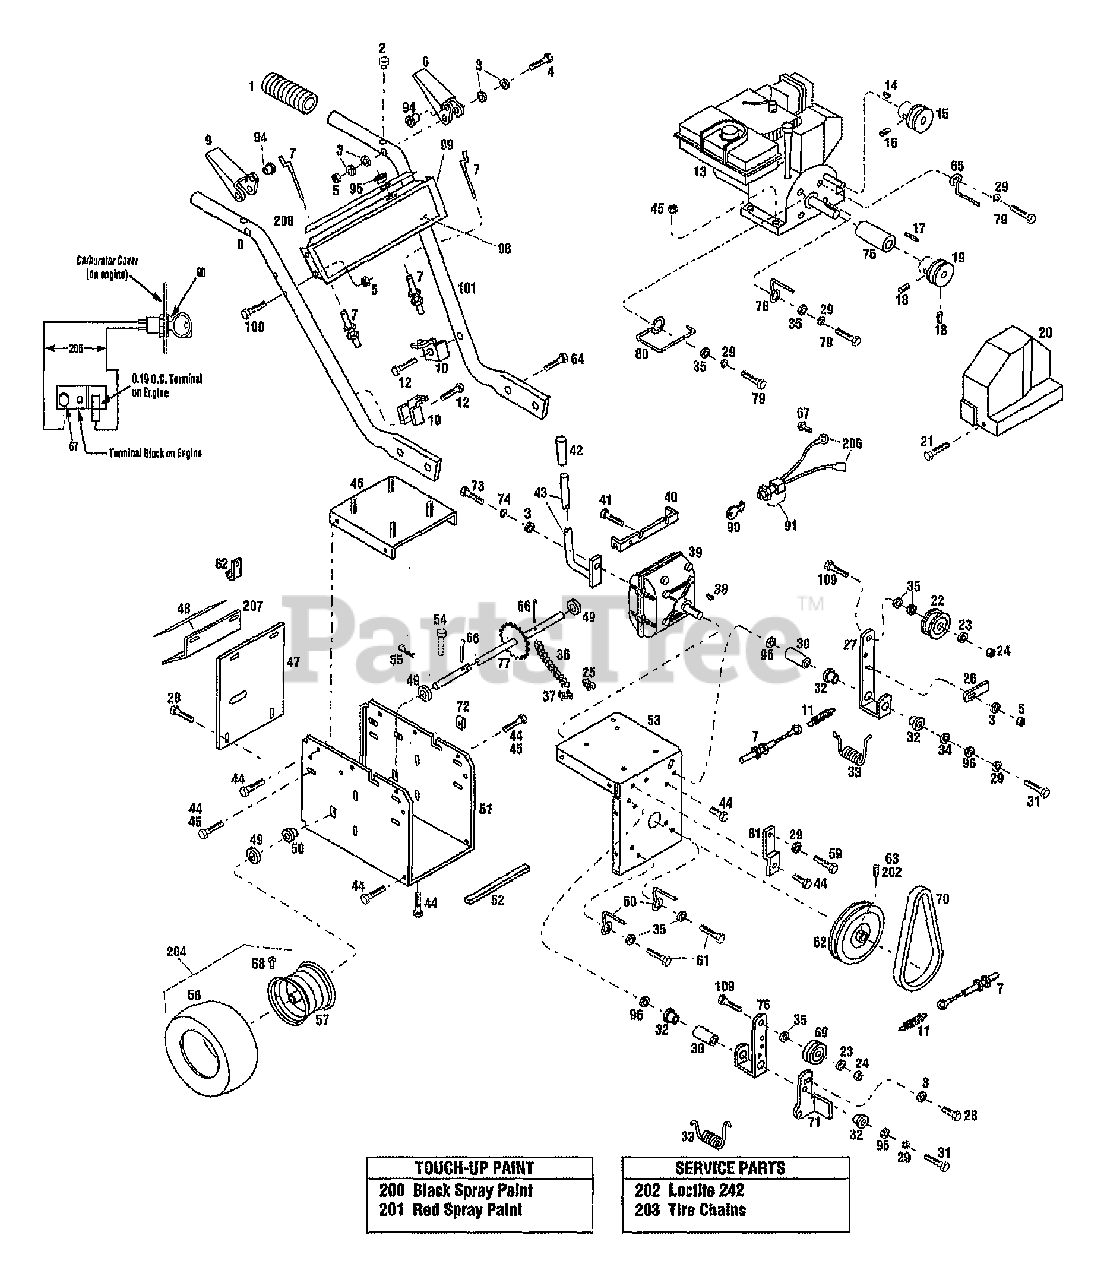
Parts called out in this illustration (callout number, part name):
1	GRIP-FLEX
2	BUMPER-RUBBER
3	WASHER-FLAT 1/4 SAE
4	SCR-HH 1/4-20X1.75 G5 ZP
5	NUT-HT LK 1/4-20
6	LEVER-CONTROL
7	CABLE-CONTROL
8	HANDLEBAR-RH
9	LEVER-CONTROL
10	BRKT-CONTROL CABLE
11	SPRING-EXT
12	SCR-FLANGE 1/4-20X3/4 GR5
13	ENGINE, TECUMSEH MODEL HSK60
14	KEY-WOODRUFF 1/8 X 5/8
15	PULLEY-PTO
16	SCR-SET 1/4-20X3/8 CONE
17	KEY-.187 SQ X .75
18	SCR-SET 5/16-18 X 5/16
19	PULLEY-ENGINE
20	COVER-BELT SC
21	SCR-TRUSS #10-24 X 5/8
22	PULLEY-IDLER
23	WASHER-LK .375 @ DEPL
24	NUT-HEX 3/8-16 ZP
25	LINK-OFFSET
26	STOP-IDLER ARM
27	ARM-IDLER WELD
28	SCR 1/4-20X.5 FL SELF TAP
29	WASHER-LK .312 ZP
30	SPACER-.5X.334X1.79
31	SCR-HH 5/16-18X2.5
32	BUSHING-.5X.5 NYLON FLNG
33	SPRING-TORSION
34	WASHER-1/2 FLAT
35	WASHER-FLAT 5/16 SAE
36	CHAIN-DRIVE
37	LINK-CONNECTOR #41 CHAIN
38	KEY-HI PRO .187X.75
39	TRANSMISSION-PEERLESS 700
40	BRKT-REINFORCMENT
41	SCR-HFLK 5/16-18X.75
42	GRIP-HANDLE
43	HANDLE-SHIFT
44	SCR-HFLK 5/16-18X.50 ZP
45	NUT-HFLK 5/16-18 ZP
46	ASSM-DOUBLER PLATE
47	COVER-REAR
48	DECAL-SHIFT
49	WASHER-FLAT
50	BEARING-FLANGE
52	PAD-RUBBER
53	ASSM-FRAME COVER
54	PIN-CLEVIS .25X1.88
55	PIN-CLIP .08
56	TIRE-4.1/3.5X6
57	RIM-WHEEL
58	STEM-VALVE
59	SCR-HH 5/16-24X.75 G5 ZP
60	GUIDE-BELT
61	SCR-HHC 5/16-18X.75 GR 5 ZP
62	SHEAVE-TRANS
63	SCR-SET SQ 5/16-18X5/8
64	SCR-HFLK 5/16-18X.62 G5ZP
65	GUIDE-BELT
66	PIN-COTTER .120X1.25 ZP
67	SCR 10-32
69	IDLER-FLAT
70	BELT-V
71	ARM-BRAKE
72	NUT-SPEED #10
73	SCR-HH 1/4-28X.75 G5 ZP
74	WASHER-LK .25 ZP
75	SPACER-1.03X.875X1.25
76	ARM-IDLER
77	AXLE-WELD
78	GUIDE-BELT
79	SCR-HH 5/16-24X.75 G5 ZP
80	GUIDE-BELT
81	BRKT-ENGINE SUPPORT
82	CLAMP-CABLE
91	SWITCH-IGN W/HDW & KEYS
94	BEARING-NYLINER
95	GROMMET-FLIP
96	WASHER-.75X.312X.065 ZP
98	DECAL-LOGO 42027
99	CONSOLE
100	SCR-HH 1/4-20X1.5 G5ZP
101	HANDLEBAR-LH
109	SCR-CARR 3/8-16X1.75 G5 ZP
200	PAINT-RED SPRAYCAN POWDER
201	PAINT-BLACK SPRAY
202	LOCTITE-242 (.5 ML TUBE)
203	CHAINS-TIRE (PAIR)
204	ASSM-WHEEL & TIRE
205	KIT-SVC 6HP SNOWTHROWER
206	ASSM-WIRE LEAD
207	BRKT-SHIFT DECAL
208	DECAL-INST
